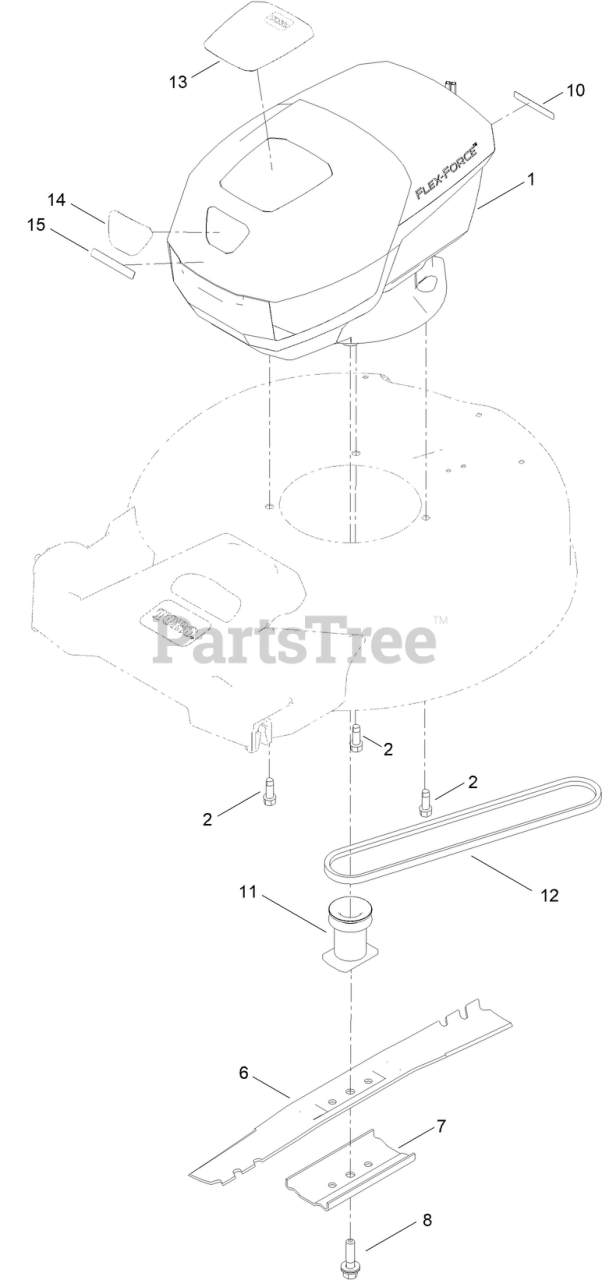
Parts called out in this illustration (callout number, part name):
1	MODULE-MOTOR
2	SCREW-TAPTITE
6	BLADE-21IN (MULCH, HS)
7	SUPPORT-BLADE
8	BOLT-BLADE
10	DECAL-PROP 65, SHORT, TRILINGUAL
11	DRIVER-BLADE
12	BELT-V
13	DECAL-FLEXFORCE BRUSHLESS
15	DECAL-LITHIUM
